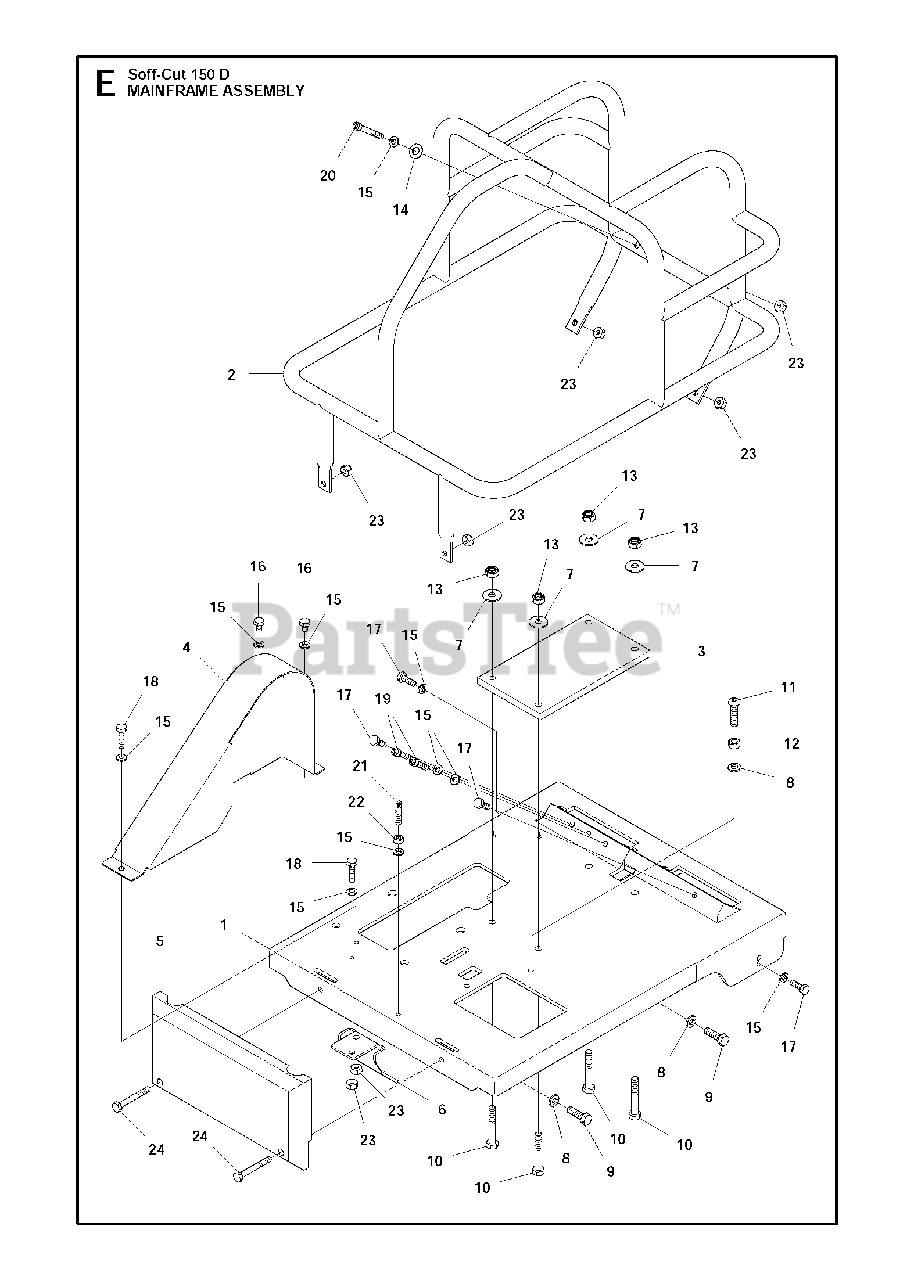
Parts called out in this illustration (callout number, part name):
7	FLAT WASH 5/16 USS ENGINE/BIG
9	HEX BOLT 5/16-18-1 CAD GR 5
13	NYLOC NUT 5/16-18 CAD PL.
23	NYLOC NUT 1/4-20 CAD PL.
